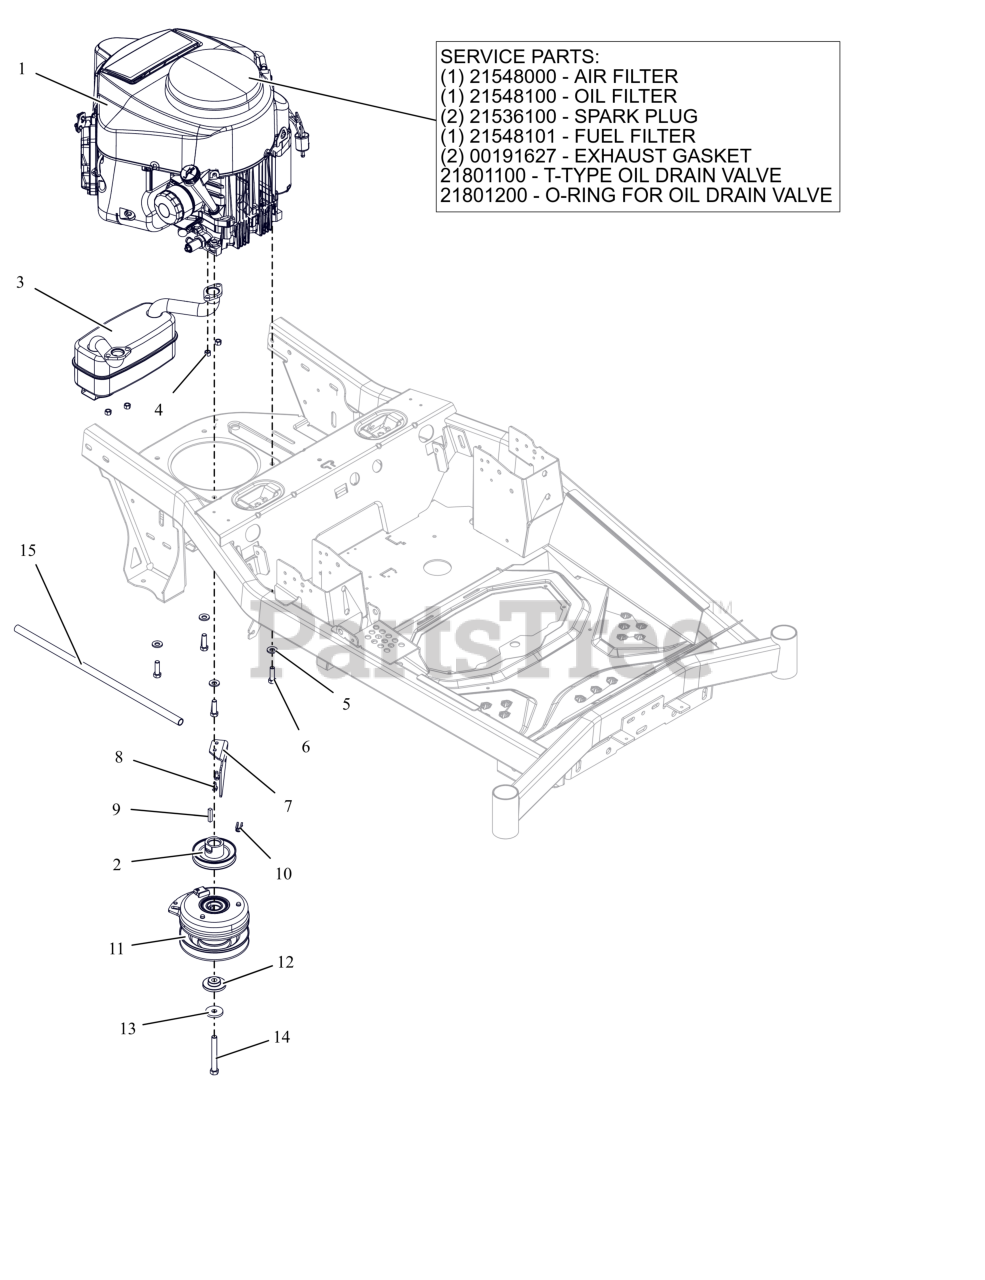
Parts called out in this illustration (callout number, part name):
1	ENGINE, KAWASAKI FR651V
1	AIR FILTER, KAWASAKI FR
1	OIL FILTER, KAWASAKI FR
1	PLUG, SPARK
1	FUEL FILTER-KAWASAKI FR
1	GASKET, MUFFLER S/O
1	VALVE- T-TYPE OIL DRAIN
1	O-RING- OIL DRAIN VALVE
2	WLDMT-PULLEY-4.831OD X1.003
3	MUFFLER - KAWASAKI
4	NUT-LK-TOP-FLG M8 ZCC
5	WASHER, 3/8" SPRING DISC
6	BLT, HEX .38-16X1.25 G5 ZCC NT
7	BRKT- CLUTCH STOP
8	SCR-TAP .25-20X.50 HWH ZCC
9	KEY-SQ .25 X 1.25 X .25 SAE
10	BSHG, CLUTCH
11	CLUTCH, WARNER-IXR-18211
12	BSHG-FLG .469X1.06X.574X2.0
13	WASHER, 7/16" SPRING DISK
14	BLT- HEX .44-20X3.50 G8 ZCC NT
15	HOSE- OIL DRAIN
